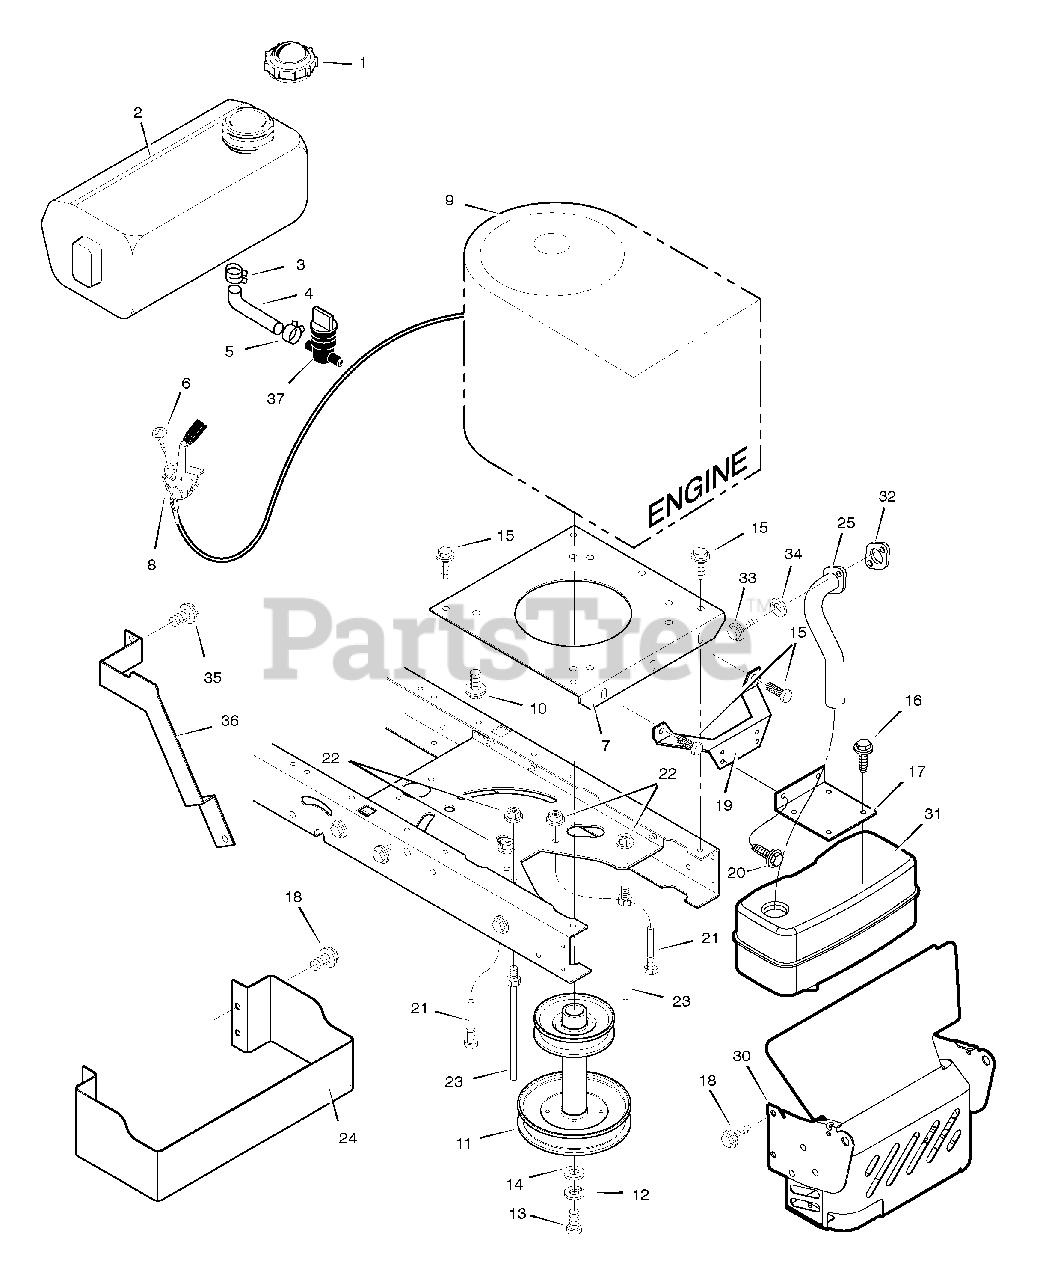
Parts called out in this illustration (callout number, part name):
1	Fuel Cap
2	Fuel Tank
3	Hose Clamp
4	FUEL LINE (Cut to length)
5	Hose Clamp
7	Plate, Engine
8	Throttle Control
9	Engine, Briggs & Stratton *
10	BOLT, Engine Mount
11	Stack Pulley Assembly
12	LOCKWASHER
13	BOLT, Hex
17	Bracket, Muffler
19	Bracket, Muffler Mount
21	GUIDE, Belt
22	NUT, Flange
23	GUIDE, Belt
24	GUARD, Heat Shield
25	Exhaust Tube, Single
30	SHIELD, Heat
35	BOLT, Washer Hex Head
36	GUARD, Exhaust Pipe
37	Valve, Fuel Shut-Off
